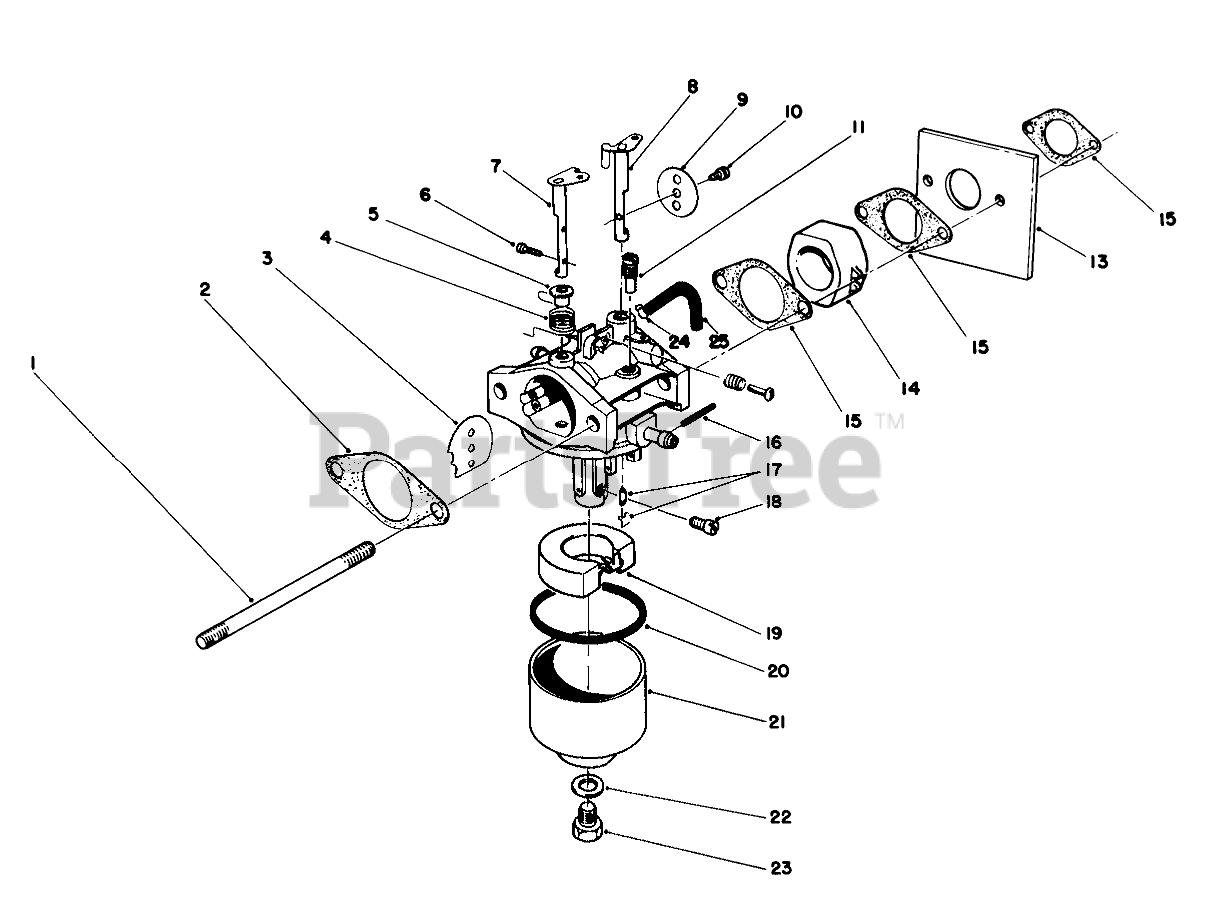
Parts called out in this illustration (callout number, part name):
1	STUD-CARBURETOR
2	GASKET-AIR CLEANER
3	PLATE
4	SPRING
5	BUSHING
6	SCREW
7	SHAFT-CHOKE
8	SHAFT
9	PLATE
10	Screw-Throttle
11	PILOT JET
13	SHIELD-CARBURETOR
14	INSULATOR-CARBURETOR
15	GASKET-CARB
16	PIN-HINGE
17	NEEDLE
18	JET-MAIN
19	FLOAT
20	GASKET
21	BOWL - FLOAT
22	GASKET
23	SCREW
24	CLAMP
25	VENT TUBE
